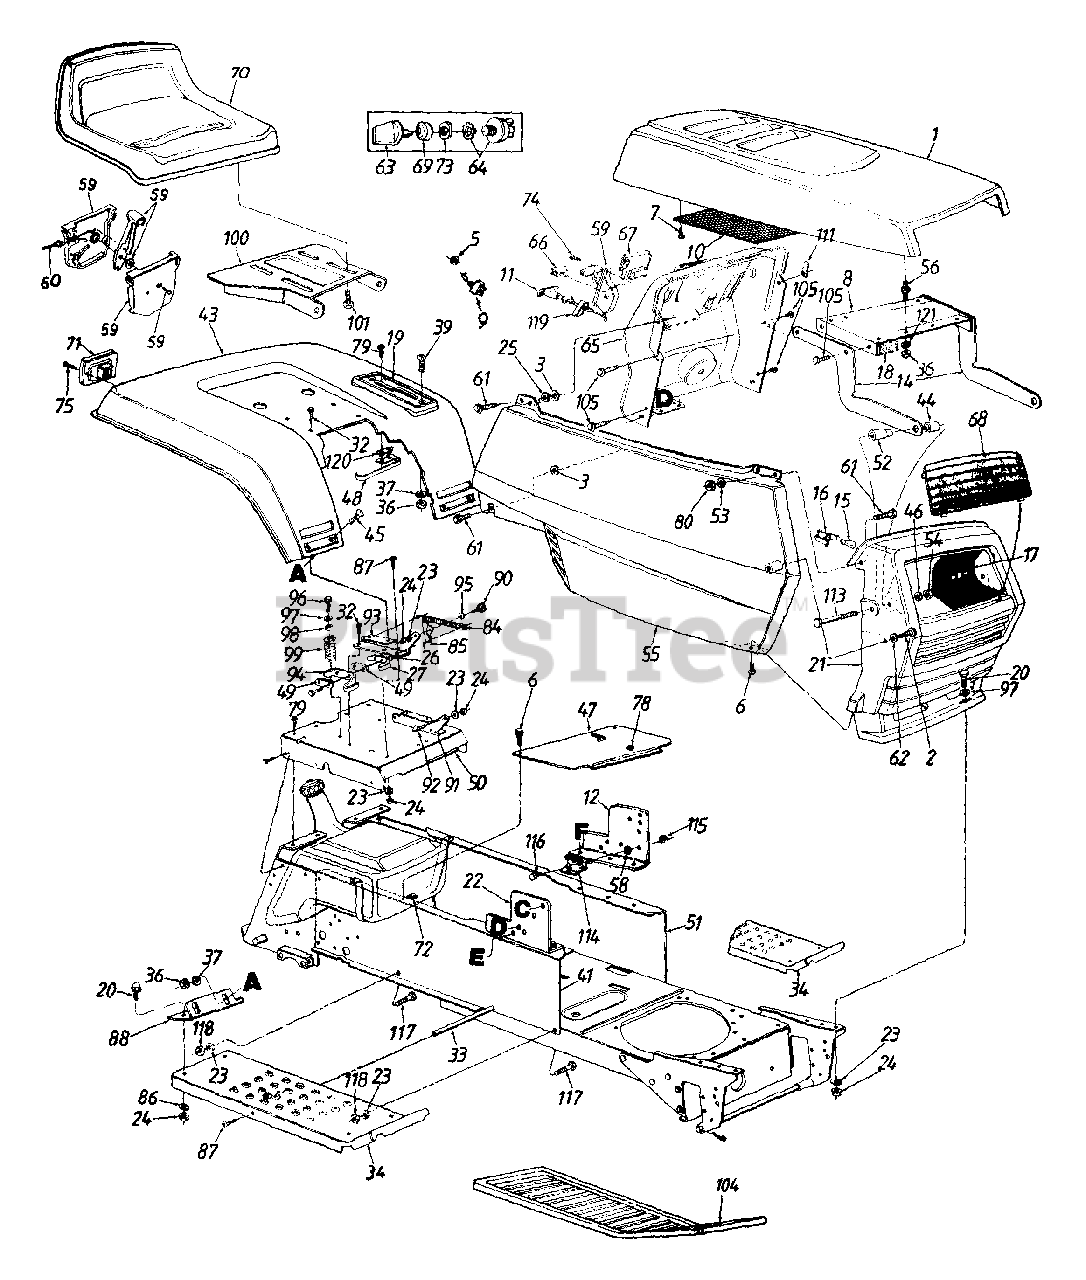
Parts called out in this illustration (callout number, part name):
1	Hood
2	Hex Wash. B-Tap Scr. 1/4 x .62" Lg.
3	Bolt Retainer 1/4" I.D.
5	Hex Nut 1/2-27 Thd.
6	Truss Mach. B-Tap Scr. #10 x .5" Lg.
7	Hex Wash Hd. AB-Tap Scr. #8 x .5" Lg.
11	Choke Control
16	Twist Lock - Lamp Socket
17	Reflector - Headlight
19	Speed Control Index Brkt.
20	Hex Bolt 5/16-18 x 1.0" Lg.
21	Grille
24	Hex Nut 5/16-18 Thd.
25	Fl-Wash. 1/4" I.D. x .93" O.D.
26	Insulator Boss Plate
27	Seat Spring Switch
32	Hex Wash. Hd. AB-Tap Scr. 5/16 x .75" Lg.
33	Running Board Rod
37	L-Wash. 1/4" I.D.
39	Truss Mach. Scr. 1/4-20 x 1.0 Lg.
41	R.H. Side Frame
45	Carriage Bolt 1/4-20 x .50" Lg.
46	Fl-Wash. .328" I.D. x .68" O.D.
49	Insulator Plate
52	Shld. Spacer .33" I.D.
53	Fl-Wash. .281" I.D. x .5" O.D.
54	Hex Cent. L-Nut 5/16-18 Thd.
55	Side Cover Ass'y. - R.H.
56	Double Ended Stud 1/4-20 Thd.
58	Ext. L-Wash. 1/4" I.D.
59	Throttle Control Box Ass'y.
60	Throttle Control Wire 39" Lg.
61	Hex Bolt 1/4-20 x .62" Lg.
62	Fl-Wash. .281" I.D. x .73" O.D.
64	Ignition Switch
65	Dash Panel
66	Light Switch
67	Ammeter
68	Lens
69	Ignition Switch Cap
70	Seat Ass'y.
71	Tail light Ass'y.
72	Speed Nut #10Z
73	Ignition Switch Nut
74	Truss Mach. AB-Tap Scr. #10 x .5" Lg.
75	Truss Hd. AB-Tap Scr. #6 x .62"
78	Snap Bushing
79	Hex Wash. Hd. AB-Tap Scr. #8 x .50" Lg.
80	Hex L-Nut 1/4-20 Thd.
84	Ext. Spring 5.31" Lg.
85	Seat Lift Brkt.
86	Bell-Wash. .345" I.D. x .88" O.D.
87	Truss Machine Scr. 5/16-18 x .75" Lg.
95	Spr.-Wash. .445" I.D.
96	Torx Hd. Tap Scr. 5/16-18 x .75"
97	Fl-Wash. .344" I.D. x 1" O.D.
99	Compression Spring
101	Hex Tap Scr. 3/8-16 x .75"
105	Hex Tap Scr. 1/4-20 x .5" Lg.
111	Speed Nut 1/4-20 Thd.
113	Hex Bolt 5/16-18 x 2.75"
114	Solenoid
115	Hex Sems Nut 1/4-20 Thd.
116	Hex Bolt 1/4-20 x .5" Lg,
117	Rib Neck Bolt 5/16-24 x .75" Lg.
118	Hex Nut 5/16-24 Thd.
119	Retainer Clip
120	Insulator Nut Plate
121	Bell-Wash. .265" I.D. x .75" O.D.
